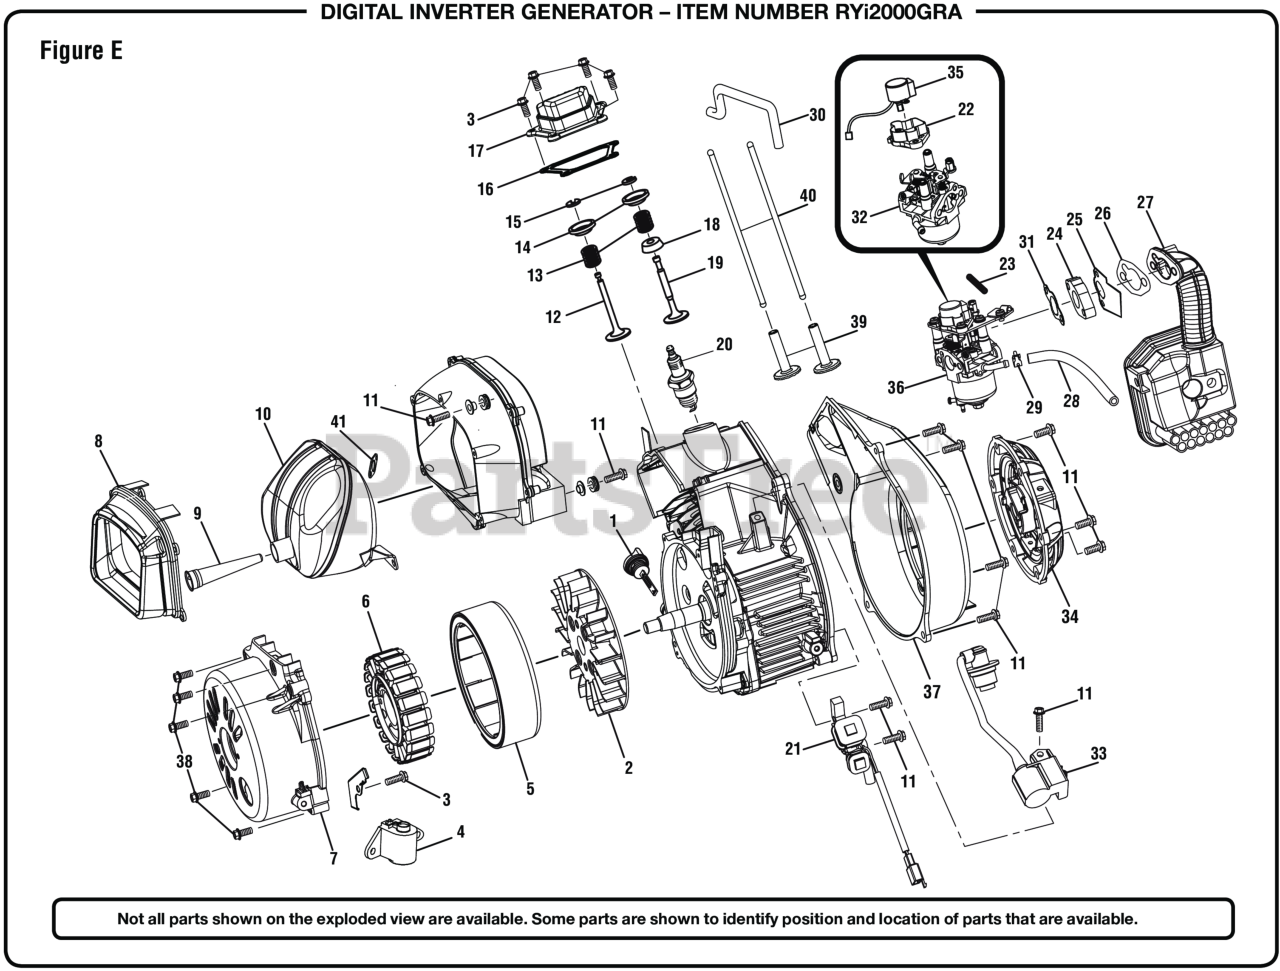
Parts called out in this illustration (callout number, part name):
1	Oil Dipstick
3	Bolt (M6 x 12 mm)
4	Low Oil Sensor
7	Alternator Cover
8	Muffler Heat Shield
9	Spark Arrestor
11	Bolt (M6 x 16 mm)
12	Exhaust Valve
13	Valve Spring
15	Valve Lock Clamp
16	Gasket (Over Head Cover)
17	Over Head Cover
18	Inlet Valve Spring Seat
19	Inlet Valve
20	Spark Plug
21	RPM Sensor
22	Governor Motor Housing
23	Compression Spring
24	Thermal Insulation Seat (Carburator)
25	Paper Gasket
26	Air Box Gasket
27	Air Filter Assembly
28	Fuel Hose (6 mm)
29	Fuel Line Clamp (7/16 in., BM903611)
30	Breather
31	Gasket (Connection Block)
32	Carburetor
33	Ignition Coil
34	Engine Recoil
35	Stepper Motor
36	Carburetor Assembly
37	Engine Cover
38	Bolt (M6 x 30 mm)
39	Lifter Valve
40	Pushing Rod
41	Gasket (Muffler)
